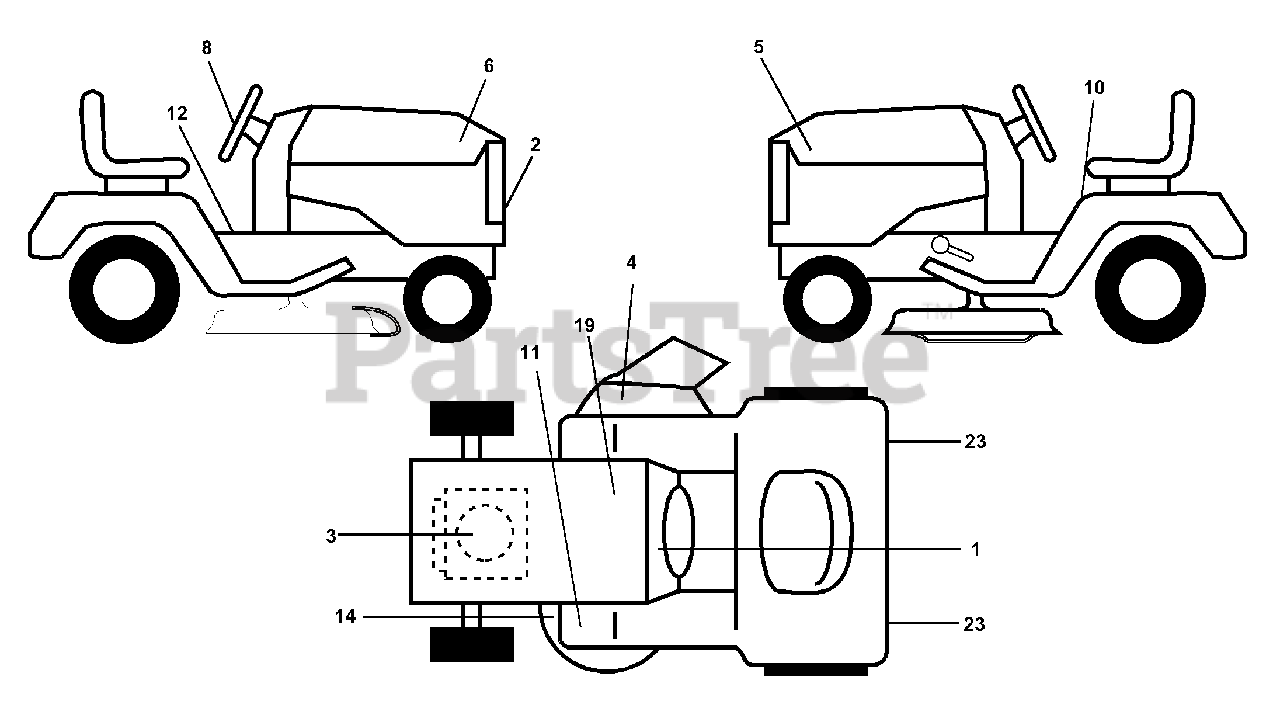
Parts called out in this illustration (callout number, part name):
1	Decal, Operating Instruction
2	Decal, Grille Husqvarna
3	Decal, HP Engine
4	Decal, Mower, Warning, Keep Hand Away
5	Decal, Hood LH GTH225
6	Decal, Hood RH GTH225
8	Decal, Wheel Steering Husq. Prem.
10	Decal, Danger
11	Decal, Clutch/Brake
12	Decal, Brake Parking Saddle
14	Decal, V-Belt Schematic
19	Decal, Battery
23	Reflector, Taillight
